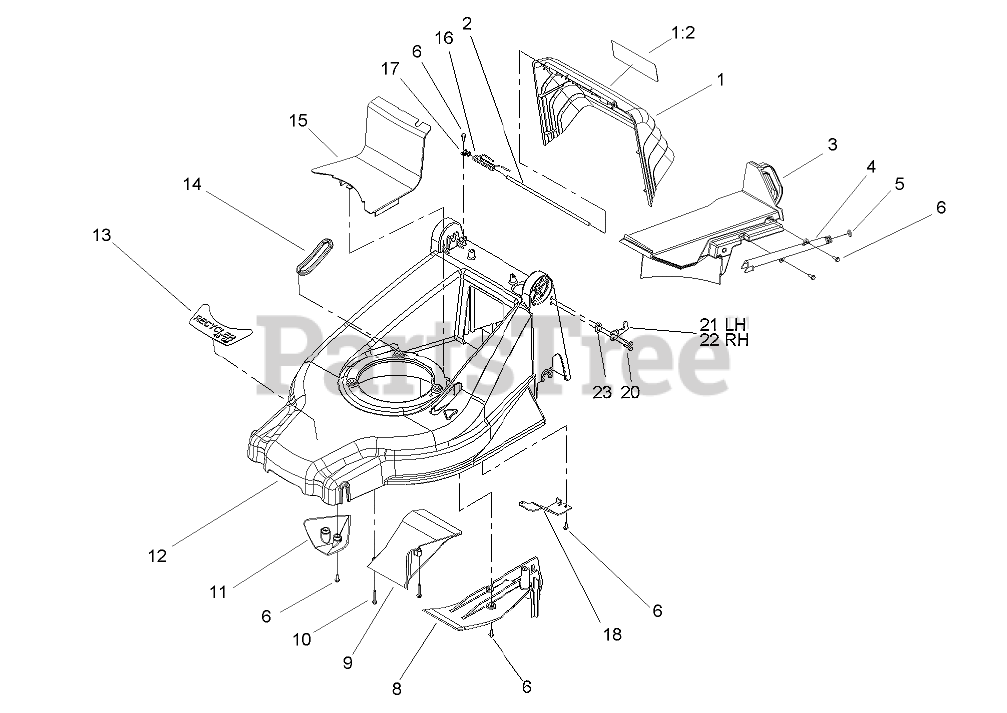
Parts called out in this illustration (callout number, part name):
1	DOOR ASM
1:2	DECAL-DANGER
2	ROD-PIVOT
3	PLUG-KICKER, RECYCLER
4	FITTING-WASHOUT
5	O-RING
6	SCREW-TAPTITE
8	COVER-KICKER, REAR
9	RAMP-DISCHARGE
10	SCREW-HWH
11	KICKER-FRONT
13	DECAL-RECYCLER
14	BOOT-HOC
15	COVER-BELT
16	SPRING-TORSION
17	CLAMP
18	BRACKET-DECK
20	SCREW-HWH
21	HOOK-LEFT
23	SPACER
